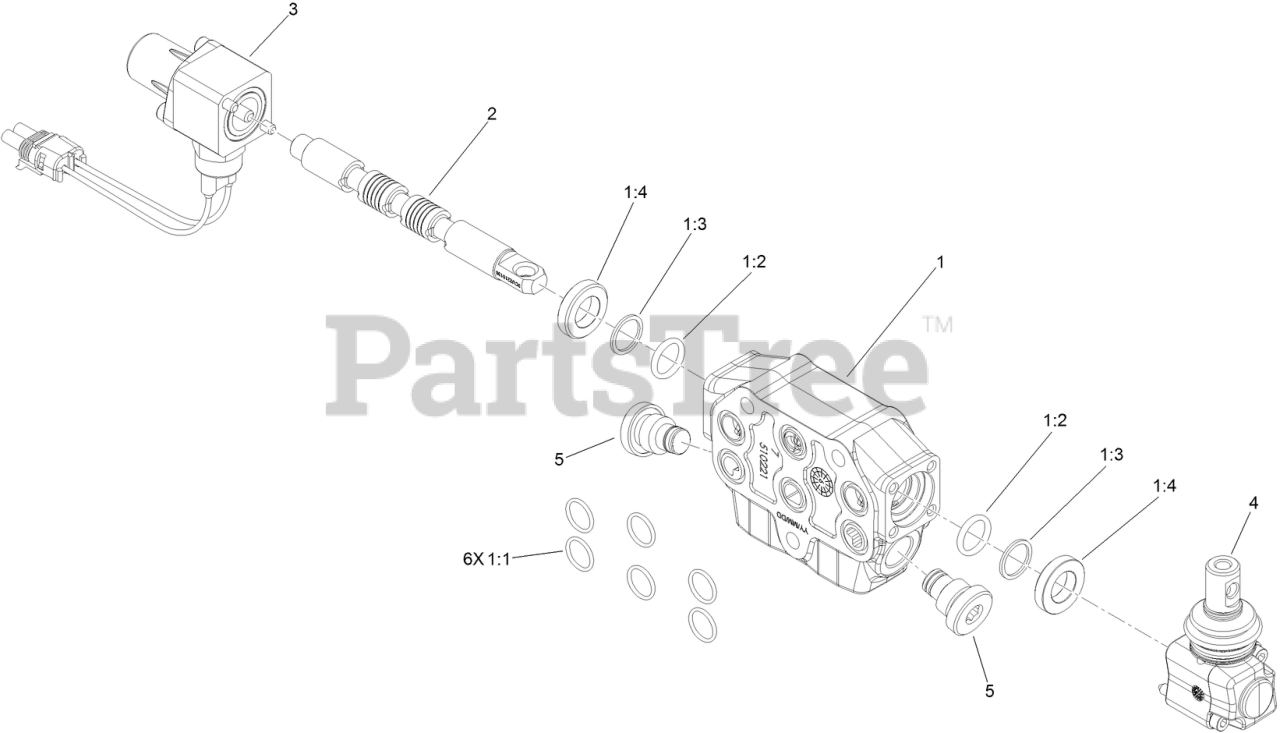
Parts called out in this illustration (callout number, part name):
1	SECTION-WORKING
1:1	O-RING
1:2	SEAL-VALVE
1:3	SEAL-VALVE
1:4	SEAL-VALVE
2	VALVE-SPOOL
3	KIT-CONTROL
4	LEVER-VALVE
